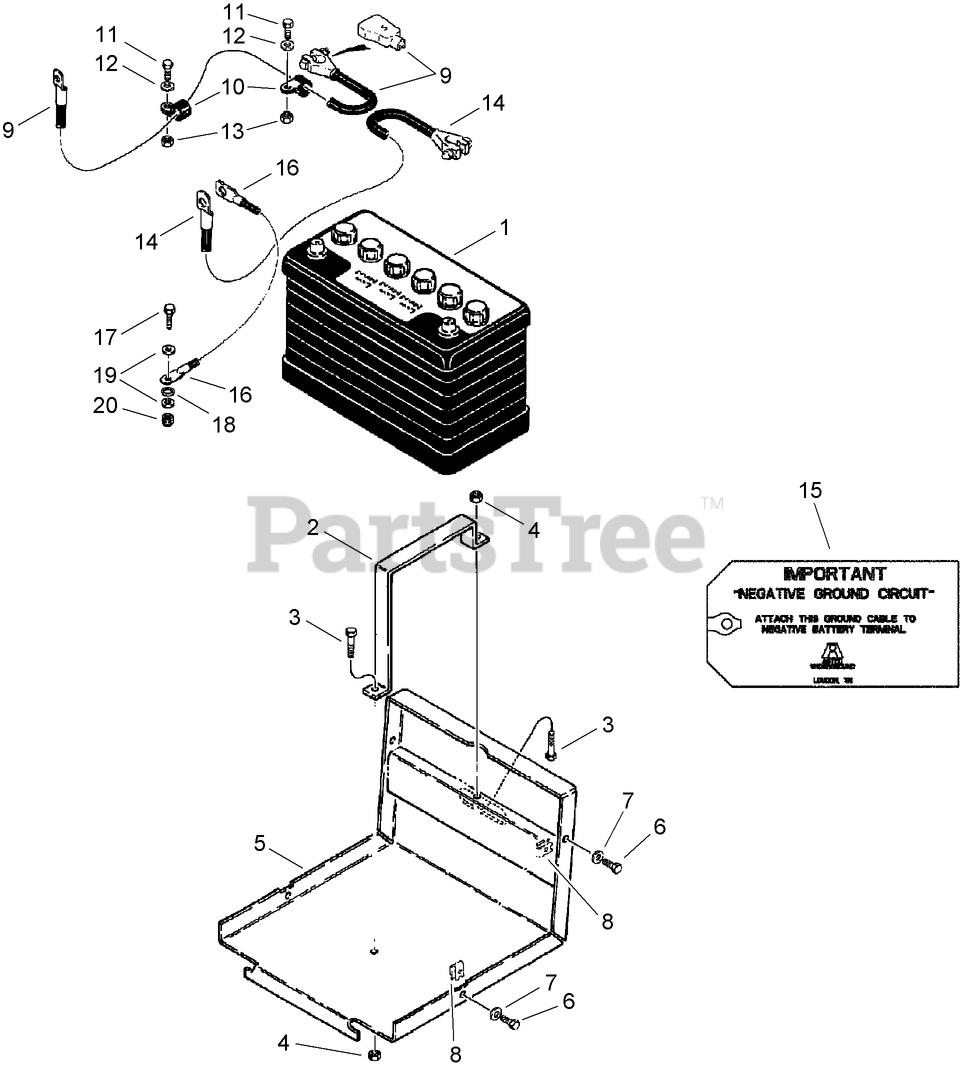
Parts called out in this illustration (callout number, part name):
1	BATTERY - 12 Volt (order from local Exide supplier)
2	BRACKET - Battery Hold-Down
3	BOLT
4	NUT-HEX
5	TRAY - Battery
6	SCREW-HH
7	WASHER-FLAT
8	NUT-SPRING
9	CABLE - Battery, Positive
10	CLAMP - Insul, 12.7mm 3/8 in Bolt ZND
11	SCREW-HH
12	WASHER-FLAT
13	NUT-HEX
14	CABLE - Battery, Negative
15	TAG - Important, Negative Ground Circuit
16	CABLE - Ground
17	SCREW-HH
18	WASHER - External Tooth Lock, 5/16 ZND
19	WASHER-FLAT
20	NUT-HEX
